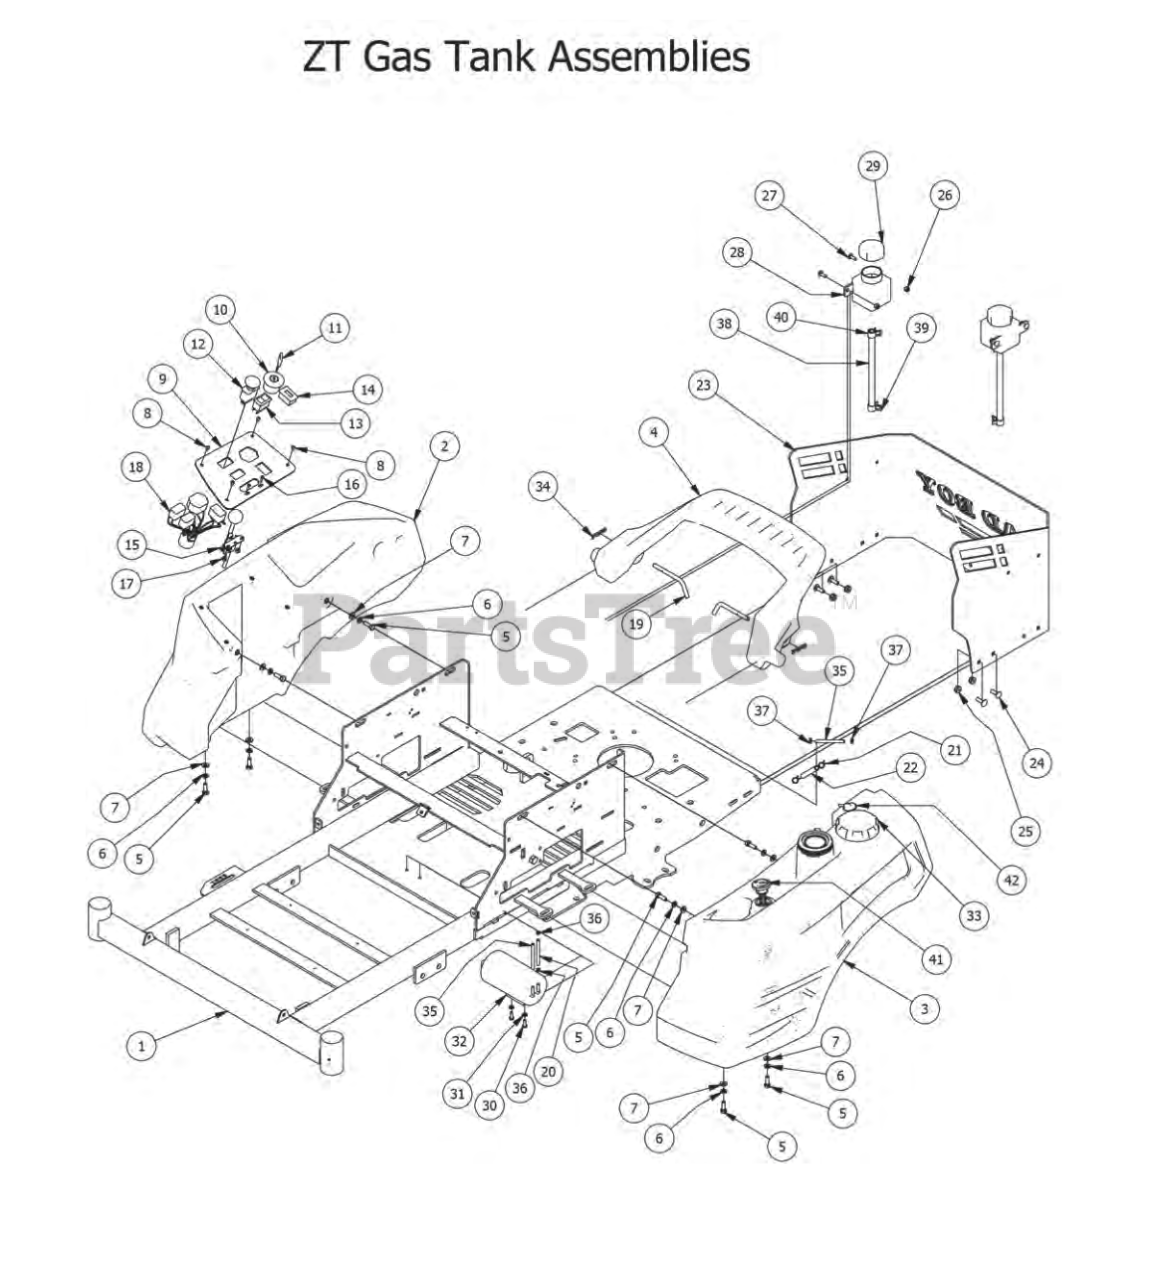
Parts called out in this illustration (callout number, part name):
1	ZT/CZT Frame 2013 Models
2	2014 ZT Right Side Console
3	2014 ZT Left Fuel Tank
4	2014 ZT Spoiler
5	5/16" x 1" Bolt
6	5/16" Lock Washer
7	5/16" Flat Washer
8	10-32 x 3/8" Button Socket Head Bolt
9	2014 ZT Control Panel
10	Ignition Switch
11	Ignition Key
12	PTO Engager
13	Rocker Deck Lift Switch - 2011
14	Tachometer
15	Throttle Lever Assembly
16	10-24 X 5/8 BS C/S 18-8 SS
17	10-24 Nylon Insert Locknut
18	Harness-ZT Only-2008 and up
19	Bent Pin-2014 ZT Spoiler
20	3/16 vinyl tubing
21	1/4 fuel clamp
22	1/4" fuel line hose
23	2014 ZT Rear Plate
24	5/16" x 1" Carriage Bolt
25	5/16-18 Nylon Flange Nut
26	1/4" Nylock Nut
27	1/4" x 3/4" Carriage Bolt
28	350ml Expansion Tank-CZT
29	Hydraulic Tank Cap
30	M6-1.0 X 16MM Hex Bolt
31	1/4" Lock Washer
32	Carbon Canister ZT,CZT,Outlaw
34	Cotter Ping-ZT Spoiler
35	1/4" vinyl tubing
36	3/16" Vinyl Hose Clamp
37	3/16 vinyl clamp
38	3/8 clear hose
39	1/2 Hose Clamp
40	3/8 hose clamp
41	Fuel Gauge Tanks W/downtube
42	Rollover Valve-White
